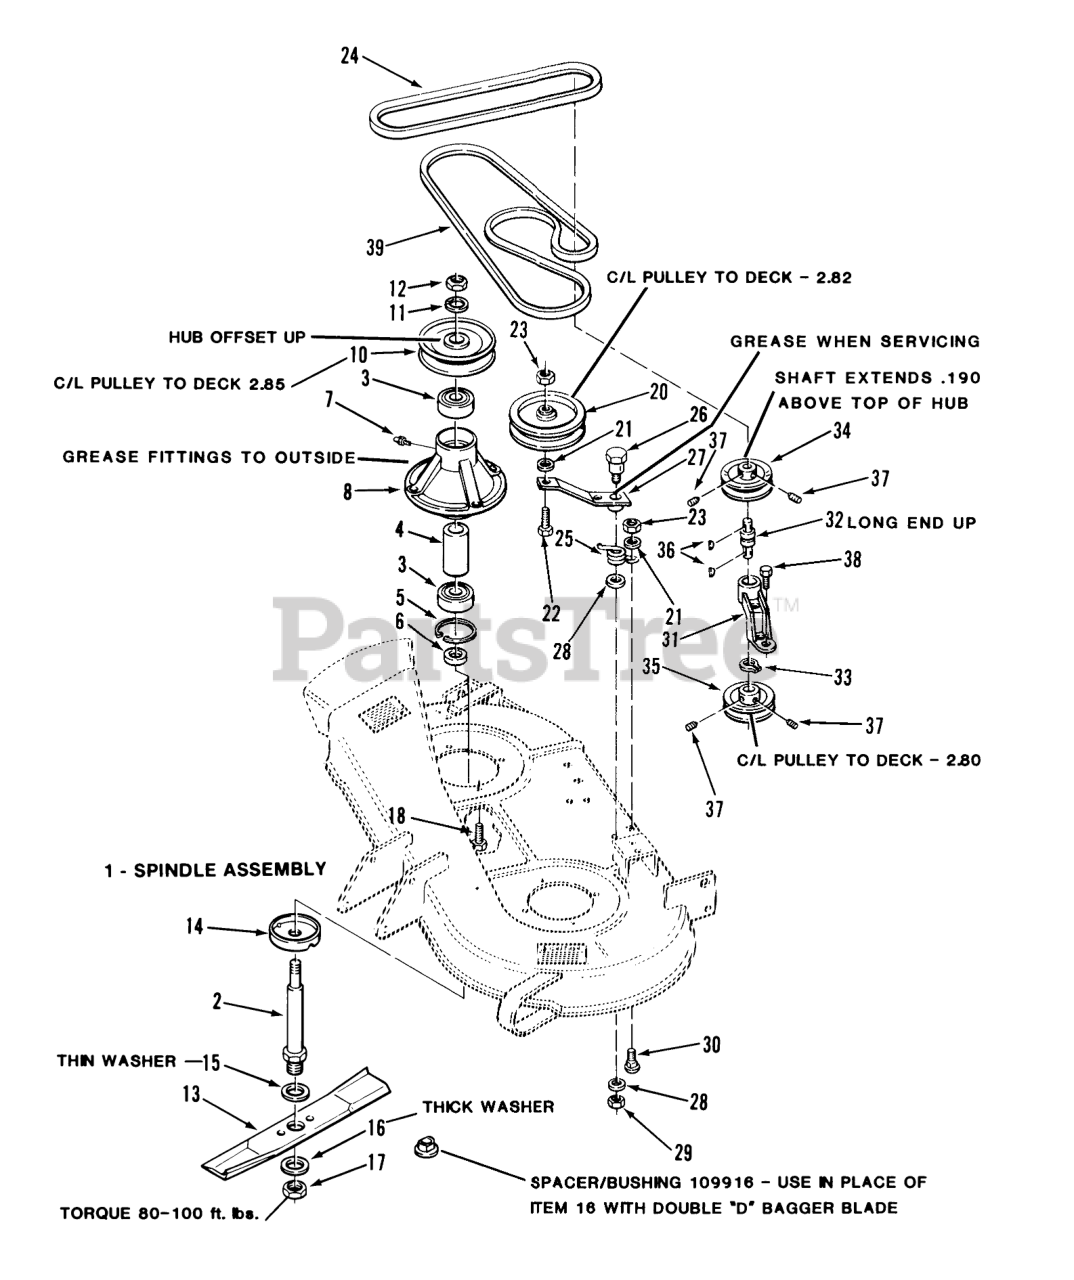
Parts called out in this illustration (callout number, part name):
1	Spindle Assembly (Includes Items 2 to 8, 14)
2	SHAFT SPINDLE
3	BEARING-BALL
5	Ring-Snap
6	SPACER-BLADE
7	Fitting-Grease
8	HOUSING SPINDLE
10	PULLEY BLADE
11	Lockwasher
12	Jam Nut
13	ASSY BLADE KIT
14	CUP-SPINDLE
15	Washer
16	SpeciaI Washer
17	Nut-Jam
18	Bolt
20	Idler Pulley
21	Washer
22	Bolt
23	Nut
24	V-BELT
25	SPRING-TORSION
26	BOLT-SHOULDER
27	Idler Arm
28	WASHER
29	NUT-JAM(7/16-14)
30	Bolt
31	HOUSING DRIVE BRG R
32	BEARING-INT SHAFT
33	Snap Ring
34	PULLEY
35	PULLEY-SPLIT
36	KEY-WOODRUFF
37	Set Screw
38	Bolt
39	BELT-V MOWER
